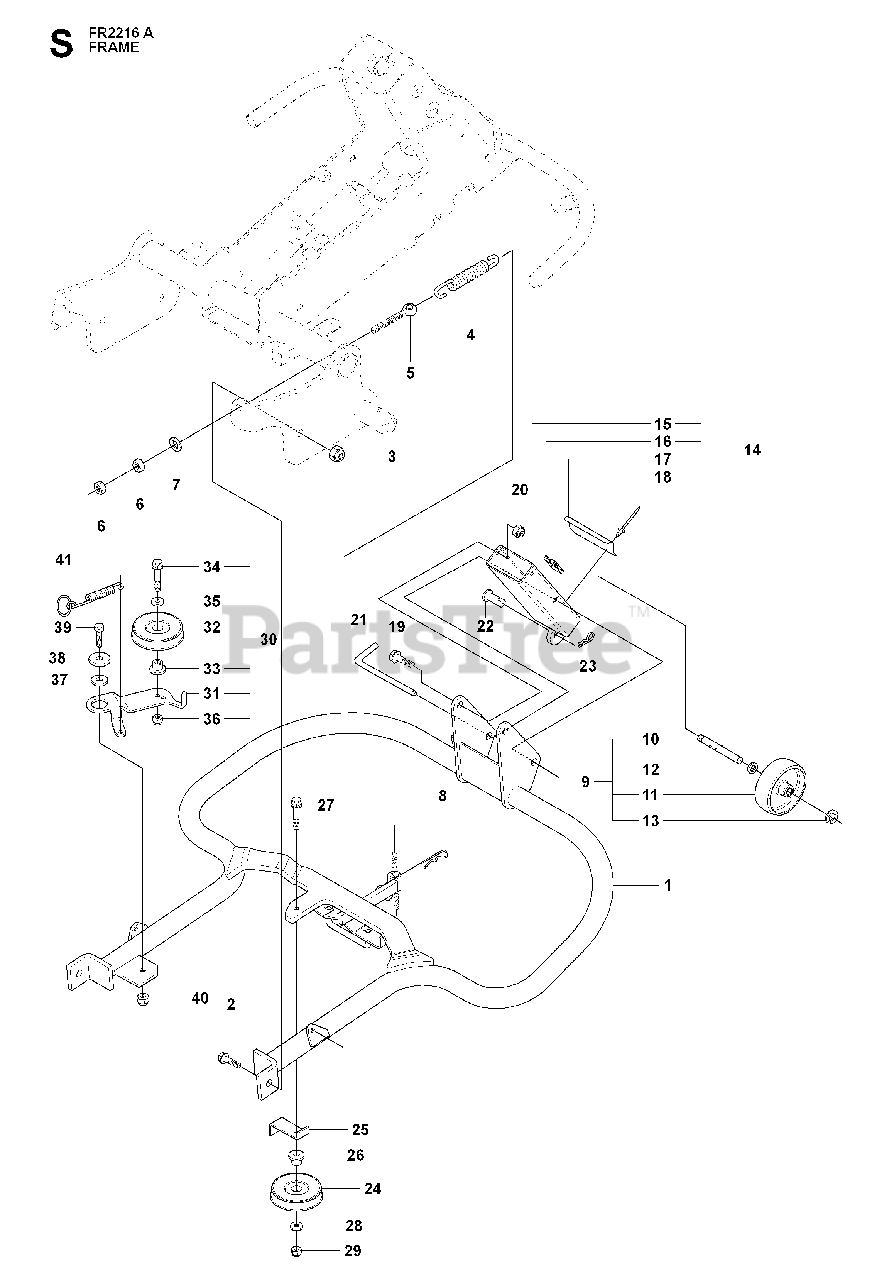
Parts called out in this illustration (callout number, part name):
7	WASHER
9	WHEEL ASSY
13	RETAINING RING
14	LINK ASSY
20	LOCKNUT M8
29	LOCKNUT M8
30	BELT TENSIONER ASSY
36	LOCKNUT M8
